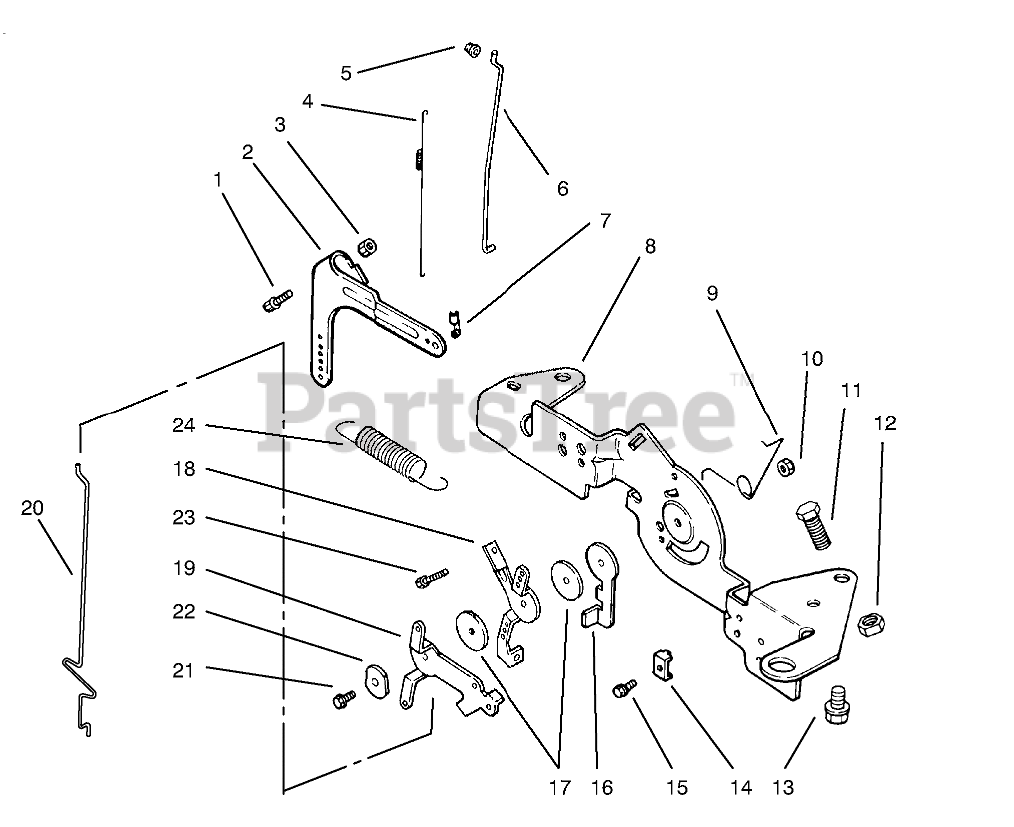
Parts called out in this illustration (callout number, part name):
1	Screw
2	Lever-Govenor
3	Nut
4	Spring-Linkage
5	Bushing-Linkage
6	Linkage-Throttle
7	Bushing-Linkage
8	Bracket-Control
9	Spring-Choke Return
10	Nut
11	Screw
12	Nut
13	Screw
14	Clamp
15	Screw
16	Lever-Actuator, Throttle
17	Washer
18	Lever-Throttle Control
19	Lever-Choke
20	Linkage-Choke
21	Screw
22	Washer-Wave
23	Screw-Hex.
24	Carriage Bolt
